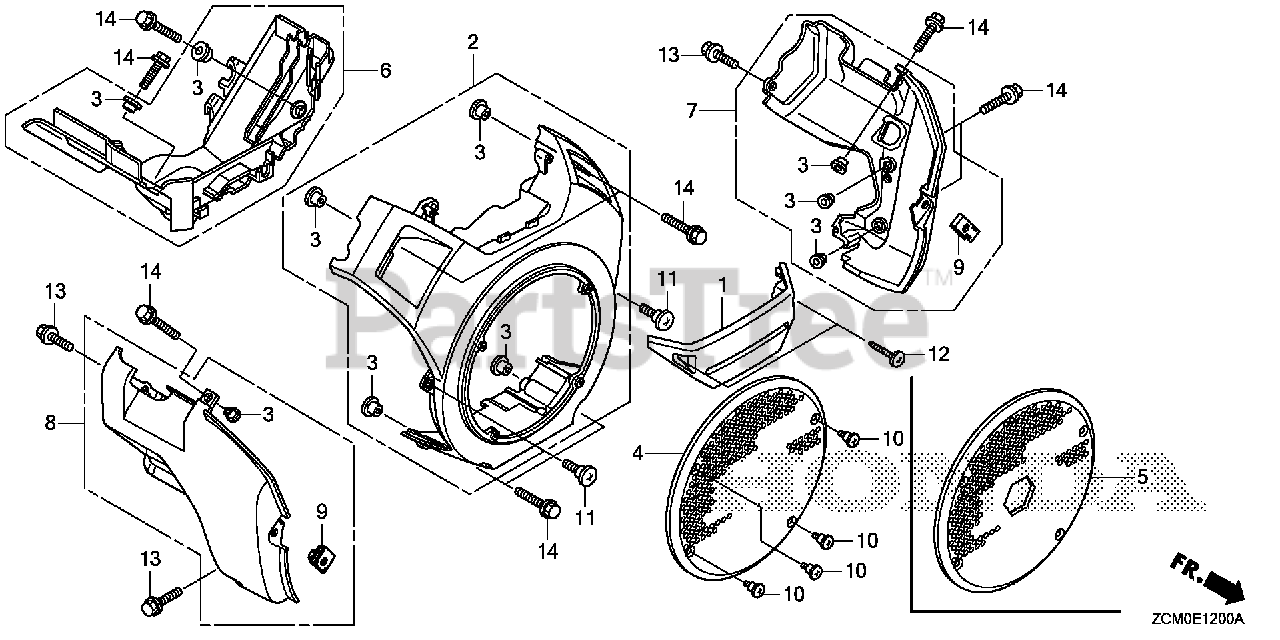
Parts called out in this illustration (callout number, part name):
1	COVER, FUEL PUMP
2	COVER, FAN *R280* (POWER RED)
2	COVER, FAN *NH1* (BLACK)
3	COLLAR, FAN COVER
4	PROTECTOR, FAN COVER
6	SHROUD (UPPER)
7	SHROUD, R. (LOWER)
8	SHROUD, L. (LOWER)
9	NUT, FENDER SETTING
10	SCREW, SPECIAL (4X10)
11	SCREW, SPECIAL (6X15)
12	SCREW, TAPPING (5X20)
13	BOLT, FLANGE (6X16)
14	BOLT, FLANGE (6X20)
